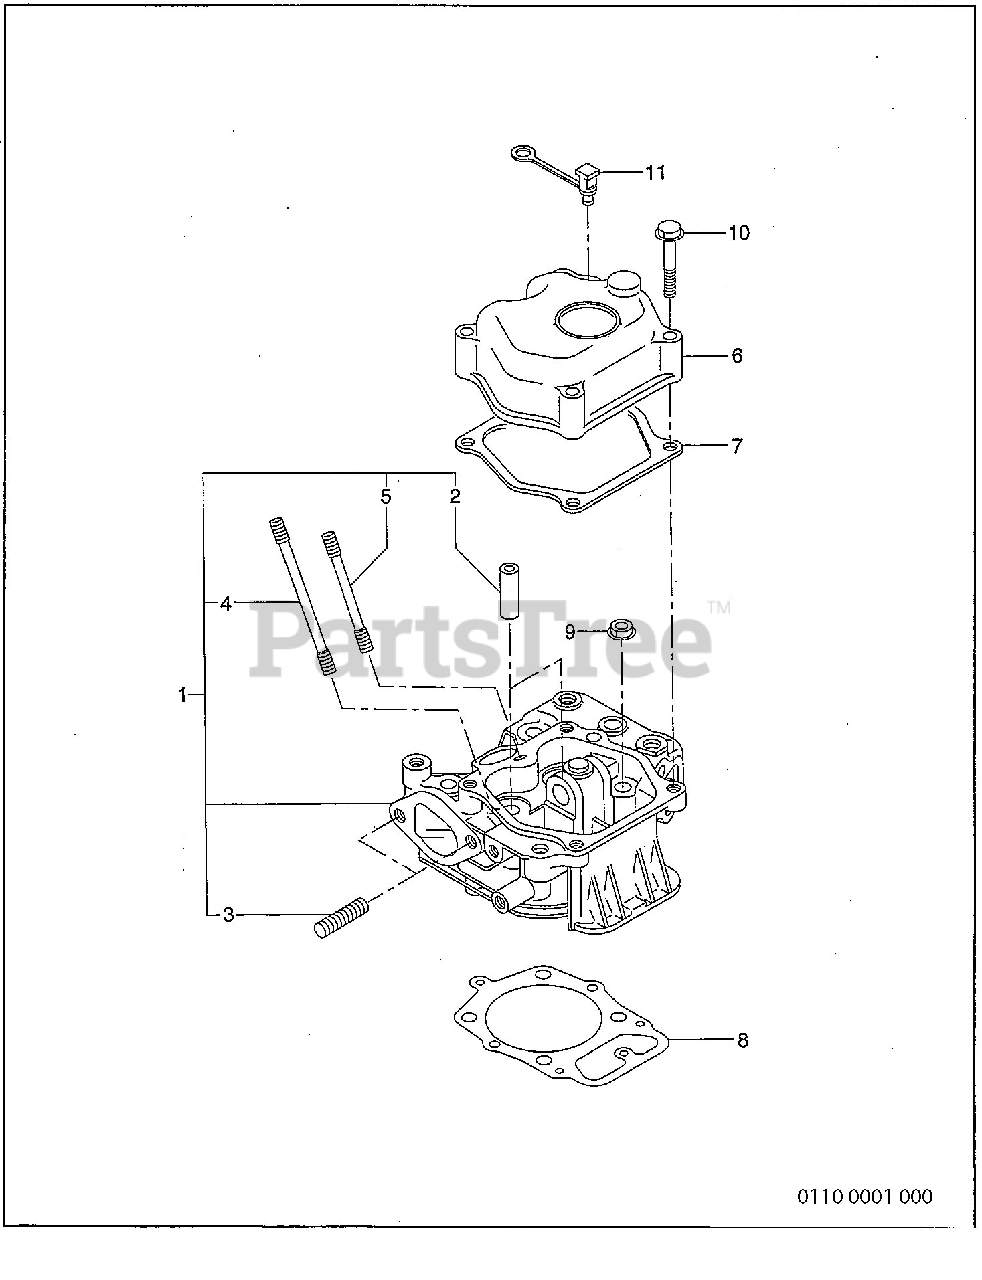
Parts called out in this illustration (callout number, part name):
1	CYLINDER HEAD ASSY
6	ROCKER COVER ASSY
7	GASKET, rocker cover
8	GASKET, head (t-0.2)
8	GASKET, head (t-0.3)
